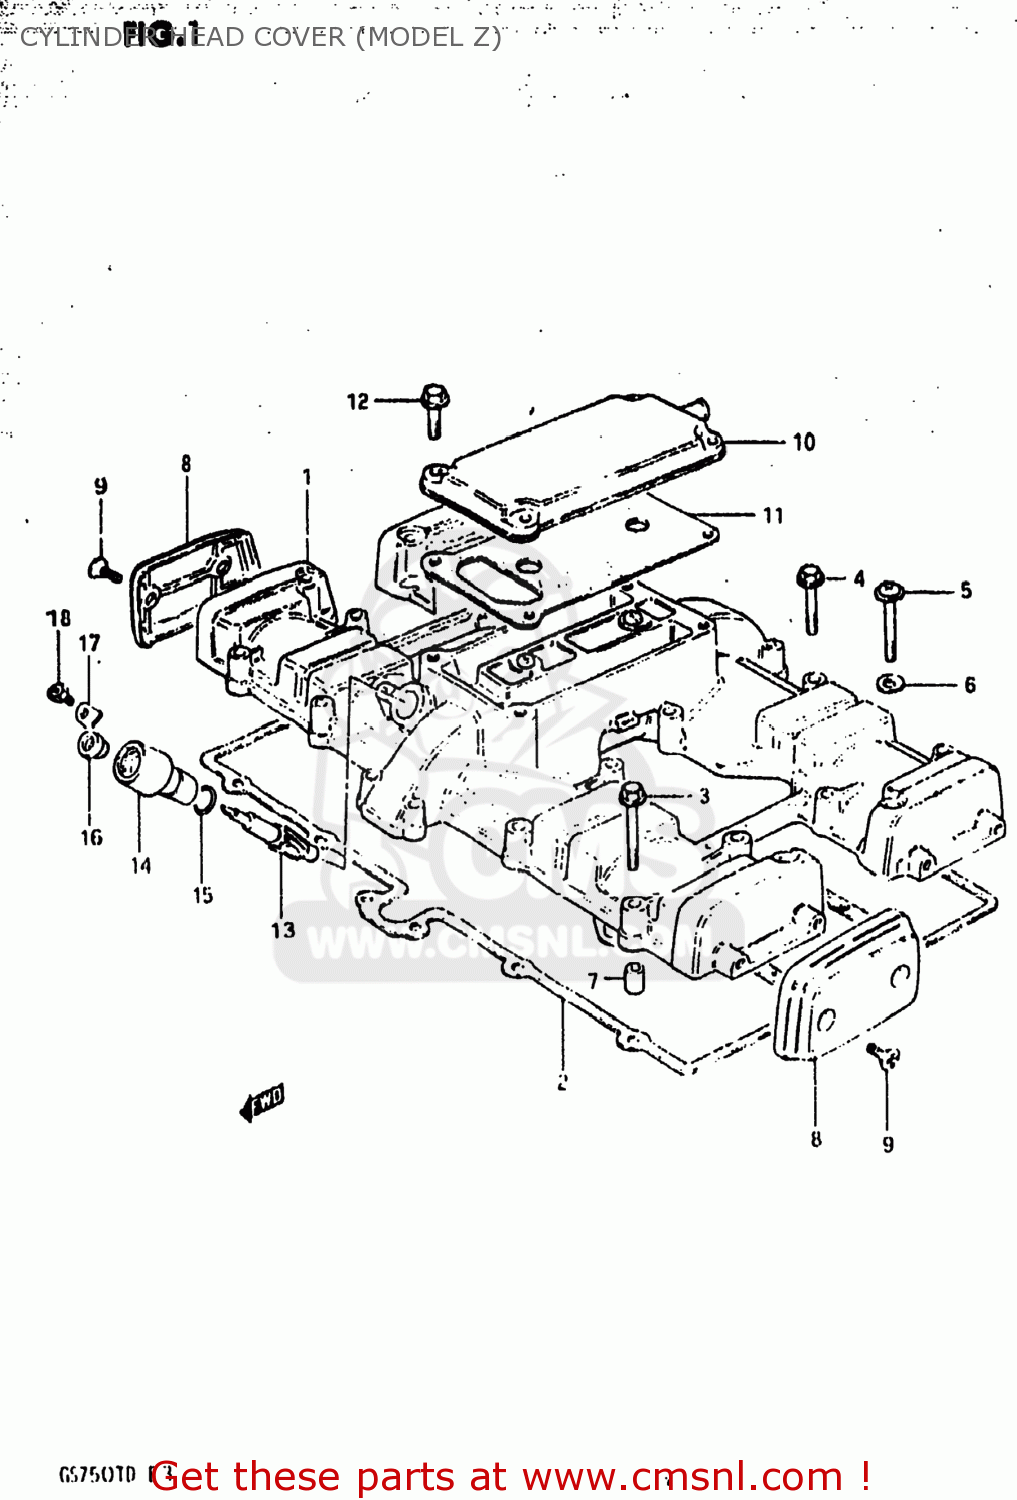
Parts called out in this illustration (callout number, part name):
1	COVER,CYLINDER HEAD
2	GASKET,CYLINDER HEAD COVER (MCA)
3	BOLT
4	BOLT 6X35
5	SCREW 6X40
6	WASHER
7	PIN(6.2X8X11)
8	CAP,CYLINDER HEAD COVER
9	SCREW(5X12)
10	COVER,BREATHER
11	GASKET (MCA)
12	BOLT,REAR
13	GEAR,TACHOMETER DRIVEN
14	SLEEVE,TACHOMETER DRIVE
15	SEAL,TACHOMETER DRIVEN
16	SEAL,OIL(5X12X8)
17	PLATE,TACH DRIVE GEAR SLEEVE
18	SCREW(5X12)
